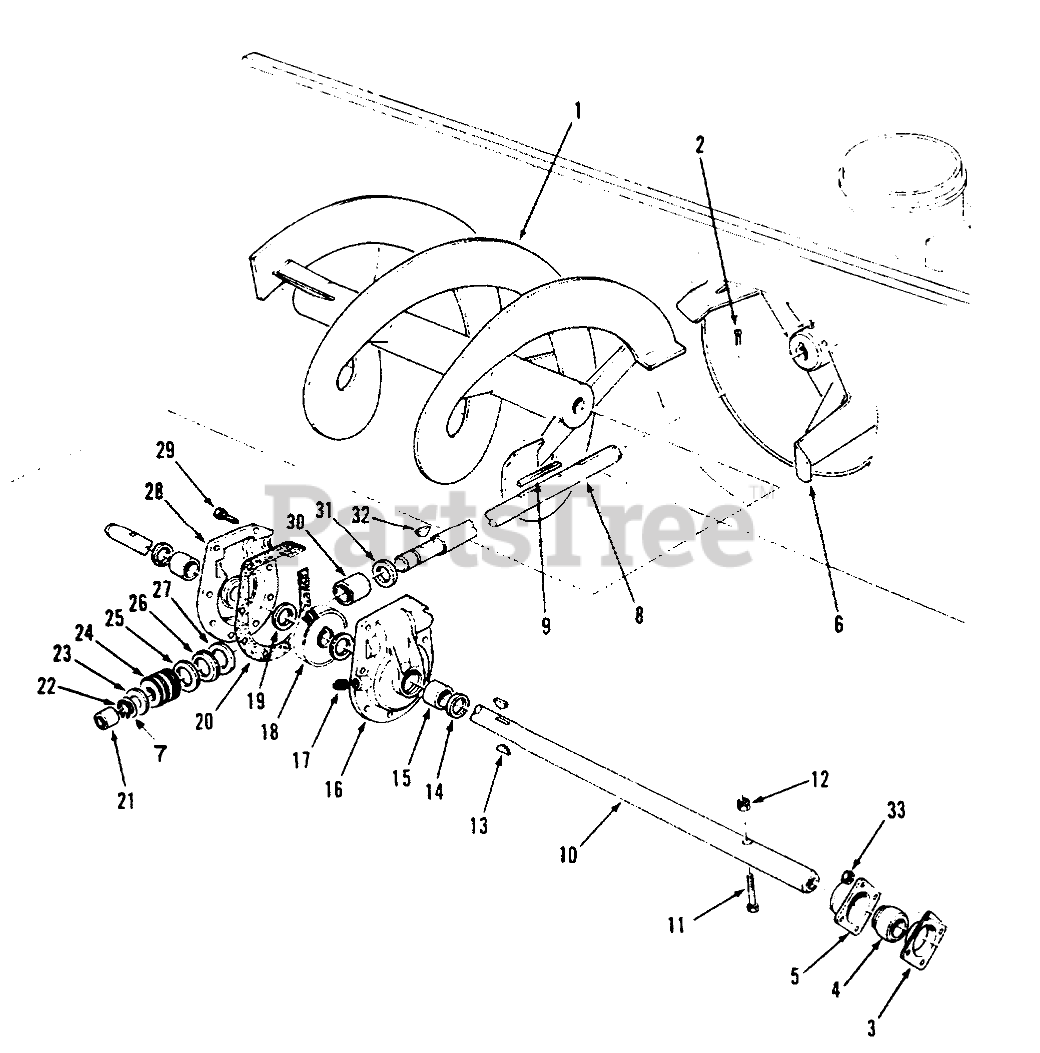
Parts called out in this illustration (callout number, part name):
1	Auger RH
2	SCREW-SET, SQH
3	BEARING-FLANGE, REAR
4	BEARING
5	BEARING-FLANGE, FRONT
6	IMPELLER ASM
7	WASHER-SHIM
8	SHAFT-IMPELLER
10	SHAFT-AUGER
11	SCREW-HH
12	NUT-LOCK, NI
13	KEY-WOODRUFF
14	SEAL-OIL
15	BUSHING
16	Assy.-Gear Case & Bushing (Incl. Ref. #14 & 15)
17	PLUG-PIPE, SQH
18	GEAR-WORM, 27T
19	WASHER-THRUST
20	GASKET-CASE, GEAR
21	BUSHING
22	Ring-Snap
23	WASHER-THRUST
25	THRUST-WASHER
26	BEARING-THRUST
27	WASHER-THRUST
28	Assy.-Gear Case & Bushing (Incl. Ref. #14 & 15)
29	SCREW-TAPTITE
30	BUSHING-SPECIAL
31	RING-QUAD
32	KEY-WOODRUFF
33	NUT-LOCK, NI
